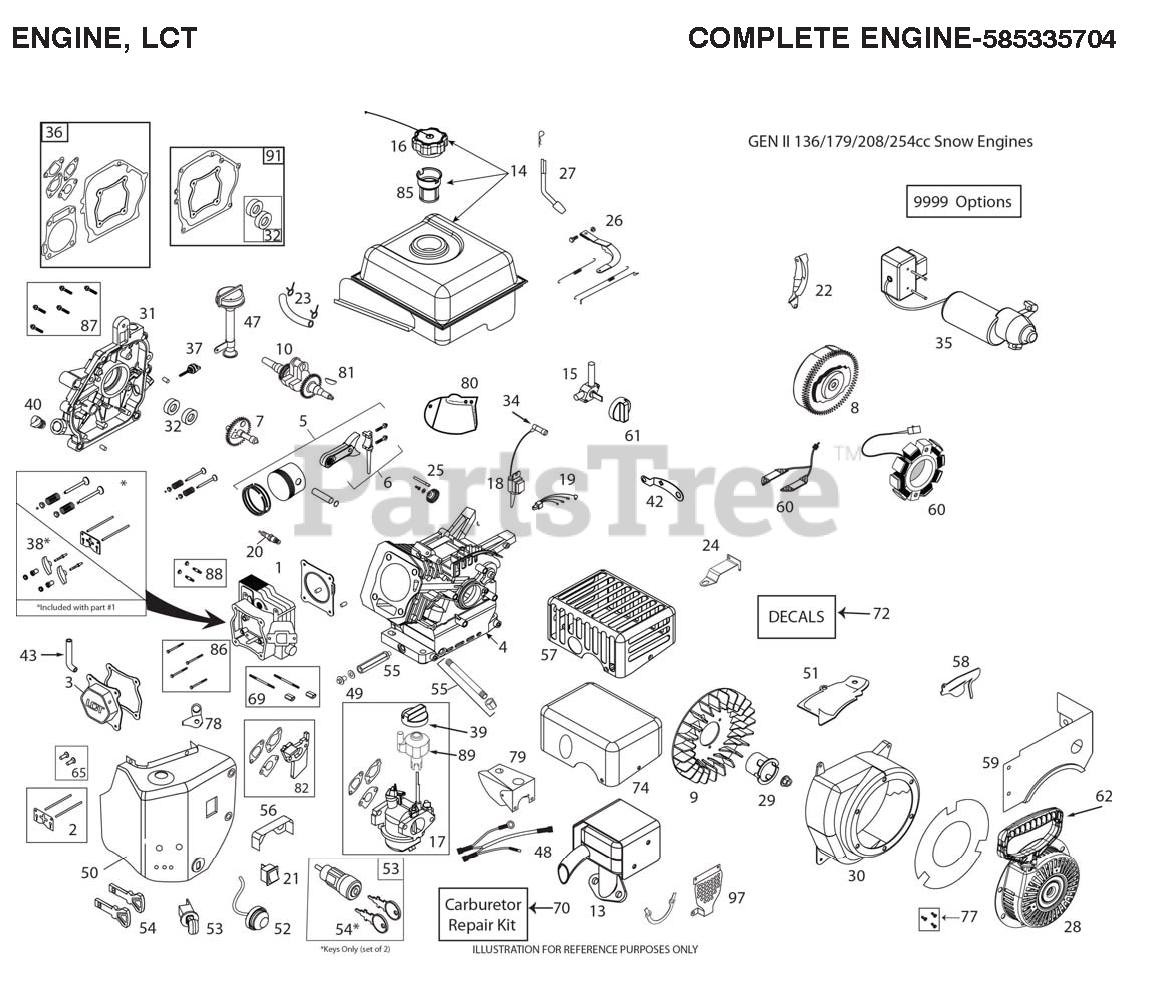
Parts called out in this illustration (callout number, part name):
1	CYLINDER.HEAD.ASM.W/GASKET.254
2	KIT.PUSH.ROD.&.PLATE.W/VC.GASK
3	COVER.VALVE.W/GASKET.254CC
4	CYLINDER LCT 254 FT OIL DRAIN
5	PISTON.&.ROD ASSEM.254CC
7	CAMSHAFT.MCR.W/GASKET.254CC
8	FLYWHEEL.ELEC.STRT.(8.MAGNETS)
9	FLYWHEEL FAN 420586
10	CRANKSHAFT.KEYED(#18).SNOW.254
13	MUFFLER.ASSEM.GEN2.SNOW.254CC
14	FUEL.TANK.SNOW.2.7L.BLACK.254C
15	FUEL.PETCOCK.SNOW(SKSN4900)
16	FUEL CAP OVERSIZED CLICK STYLE
17	CARBURETTOR LCT 254 W/IDLEDOWN
18	COIL.ING.CDI.HI TEMP.SKSNO416.
20	PLUG.SPARK.PLAT.SKSN2404.1
21	SWITCH.ON/OFF(SKSN-0403)
22	SHIELD.FLYWHEEL.ELEC.STRT.208C
23	KIT.FUEL.HOSE.208CC.SING/STAGE
24	BRACKET.SPEED.CNTRL.FIXED.254C
25	GOVENOR.GEARS ASM(SK2082900)
26	KIT.GOVERNOR.ARM.&.LINK.254CC
27	KIT.GOVERNOR.CRANK(SK208-3100)
28	RECOIL.STRT.ROUND(BLK) SNOW
29	STRTER.CUP(NON-SLOT)SKSN0601.2
30	BLOWER HSG.LCT 254 GLOSS BLK S
31	CRANKCASE.CVR.PRESS.IN.HI-OIL.
32	KIT.SEAL.OIL.2.PIECES.254CC
34	SPARK.PLUG.BOOT.SNW,SKSN4691.1
35	STARTER.EL.230C.SNO.LCT.208CC.
36	KIT.ENGINE.GASKET.254CC
38	KIT.ROCKER.ARM.W/GASKET.254CC
39	CHOKE.KNOW.SNOW(SKSN4500)
40	NON REMOVABLE PLUG
43	TUBE.BREATHER.LCT.208
47	TUBE ASSY HIGH OIL-FILL
48	WIRE.HARNESS.SNOW
49	KIT.OIL.DRAIN.PLUG(SK2089911
50	KIT.HEATER.BOX.SNOW.254CC
51	SHIELD.CYLINDER.COVER.254CC
52	PRIMER.BULB.WITH HOSE (SNOW)
53	SWITH.KEY.ASSEM.SNOW.SINGLE.ST
54	KEY SET(2 KEYS) SKSN0407.1
55	OIL PIPE DRAIN LCT 254
56	SHIELD.CARBURETOR.VAPOR
57	SHIELD.MUFFLER.CE.COMPLIANT
58	SHIELD.GOVERNOR.LINKAGE.254CC
59	FUEL TANK SKIRT SHIELD LCT 254
60	208CC 60W ALTERNATOR
61	FUEL KNOB-SNOW
62	HANDLE.RECOIL.DELUXE.LCT
65	TAPPET.KIT.LCT.208CC
69	CARB.STUDS & COUPLING KIT.SNOW
70	CARB.REPAIR.KIT.LCT.SK9900.2
74	MUFFLER GUARD.EUR./LCT.SKSN220
77	BOLT.KIT.RECOIL.LCT.ALL.ENGINE
79	COVER.CARBURETOR.SNOW
80	SHIELD.GOVERNOR.LINK.SNOW.254C
81	KEYS.FLYWHEEL.208/414CC.5PACK
82	SPACER.CARBURETOR.208CC.LCT
85	STRAINER.FUEL.TANK.LCT.208CC
86	KIT.BOLT.CYLINDER.HEAD.(4PC)
87	KIT.BOLT.CRANKCASE.COVER.6PC
88	STUD.MUFFLER.KIT.LCT
89	KNOB LCT.SKSN5325.1 SPEED
91	CRANKSHAFT GASKET KIT.LCT
97	GUARD.MUFFLER.MANIFOLD.LCT
9999	JET HIGH ALTITUDE LCT 5000 25
9999	STARTER SCREW.STARTER SWITCH B
9999	KIT.BOLT.LCT.SK9990.1
